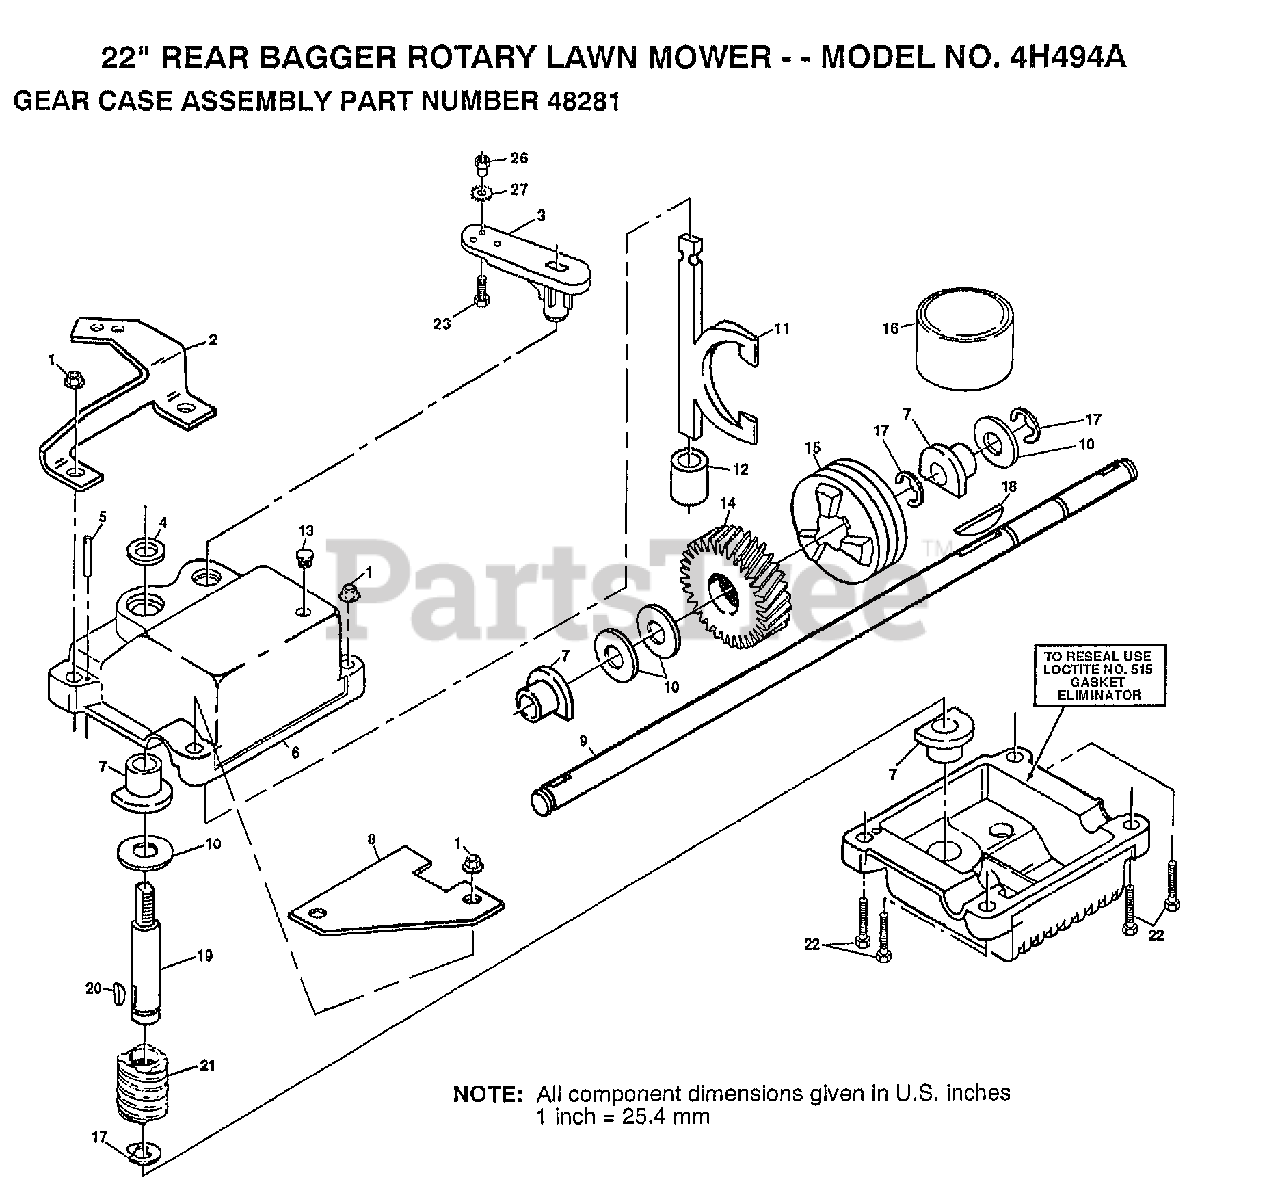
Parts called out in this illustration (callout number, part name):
1	NUT
2	"BRKT,ADJ"
4	SEAL
5	DRIVE LOK PIN
6	CASE HALF KIT PM
7	BEARING
9	DRIVE SHAFT
10	THRUST WASHER
11	CLUTCH YOKE
13	PLUG PM
14	HELICAL GEAR
17	RING T
18	HI PRO KEY
19	WORM SHAFT
20	WOODRUFF KEY
